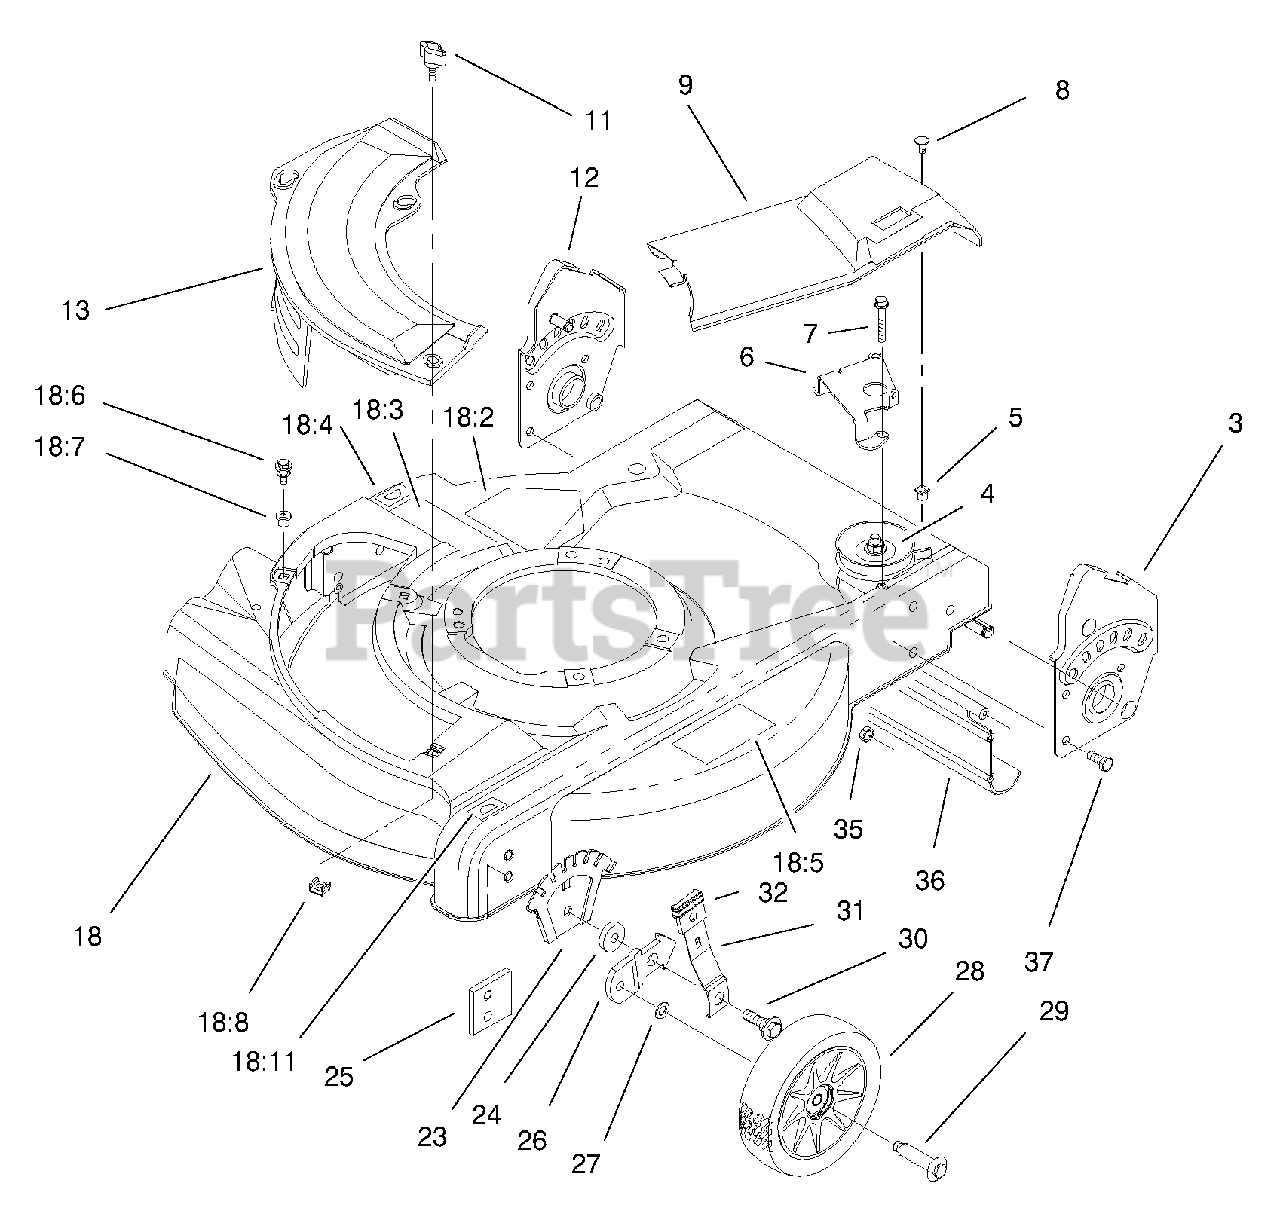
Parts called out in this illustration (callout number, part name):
3	LH Handle Bracket ASM
4	Gear Case ASM
5	Grommet
6	Guide-Transmission
7	Screw-HWHTF
9	Cover-Drive
12	RH Handle Bracket ASM
13	Plate-Mulch
18	Deck ASM
18:2	Decal-Danger
18:3	Decal-Warning
18:4	Decal-HOC, RH
18:5	Decal-Warning
18:6	Screw-Sems
18:7	Grommet-Plastic
18:8	Nut-Cage
18:11	Decal-HOC, LH
23	Plate-Height Adj
24	Washer-Wheel
25	Plate-Baffle
26	Bracket-Wheel Height Adj
28	Wheel & Tire ASM
29	Bolt-Shoulder
30	Bolt-Shoulder
31	Arm-Front Spring
32	Knob-Lever, Height Adj
35	Nut-Lock, NI
36	Shield-Trailing
37	Screw-HH
